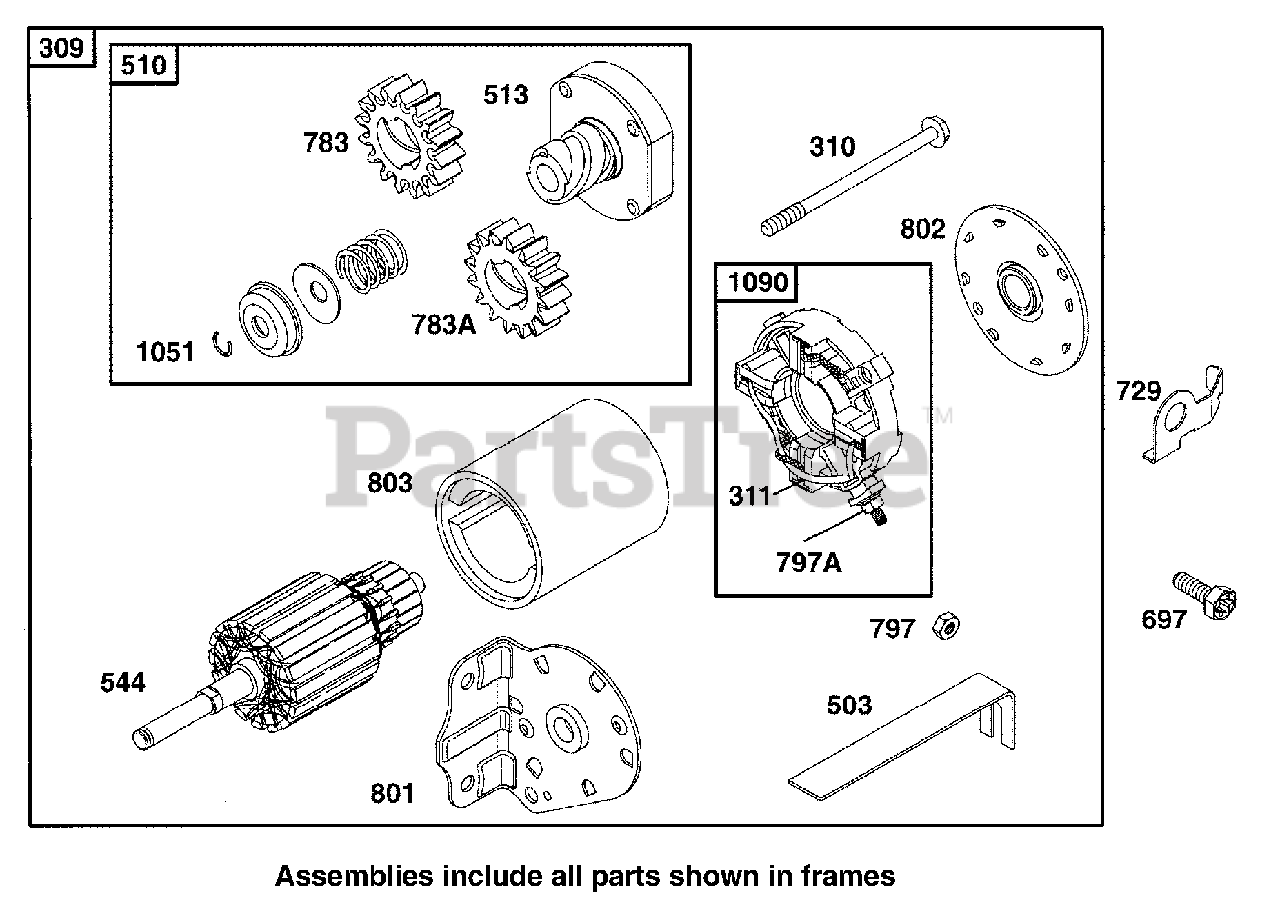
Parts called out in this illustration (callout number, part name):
309	Starter Motor
310	Bolt (Starter Motor)
503	Starter Strap
510	Starter Drive
513	Drive Clutch
544	Starter Armature
697	Screw (Starter Motor Mounting)
783	Starter Gear (For Plastic Ring Gear Only)
783A	Starter Gear (For Aluminum Ring Gear Only)
797	Nut (Starter Terminal)
797A	Nut (Starter Terminal)
801	Drive Cap
803	Starter Housing (3-5/8 Housing Length)
1051	Retaining Ring
1090	Brush Retainer
